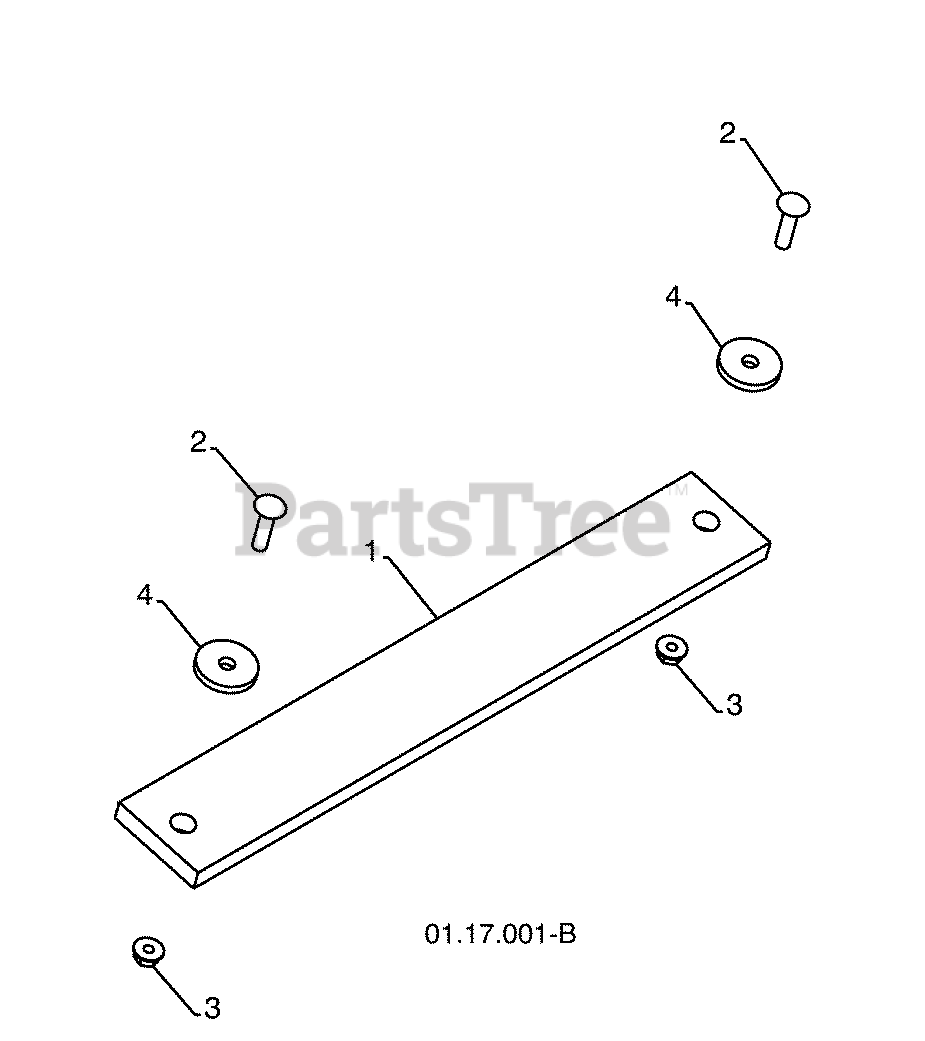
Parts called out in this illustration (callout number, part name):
1	WEIGHT BAR
2	CARRIAGE BOLT 5/16-18 X 1.25
3	NUT 5/16-18
